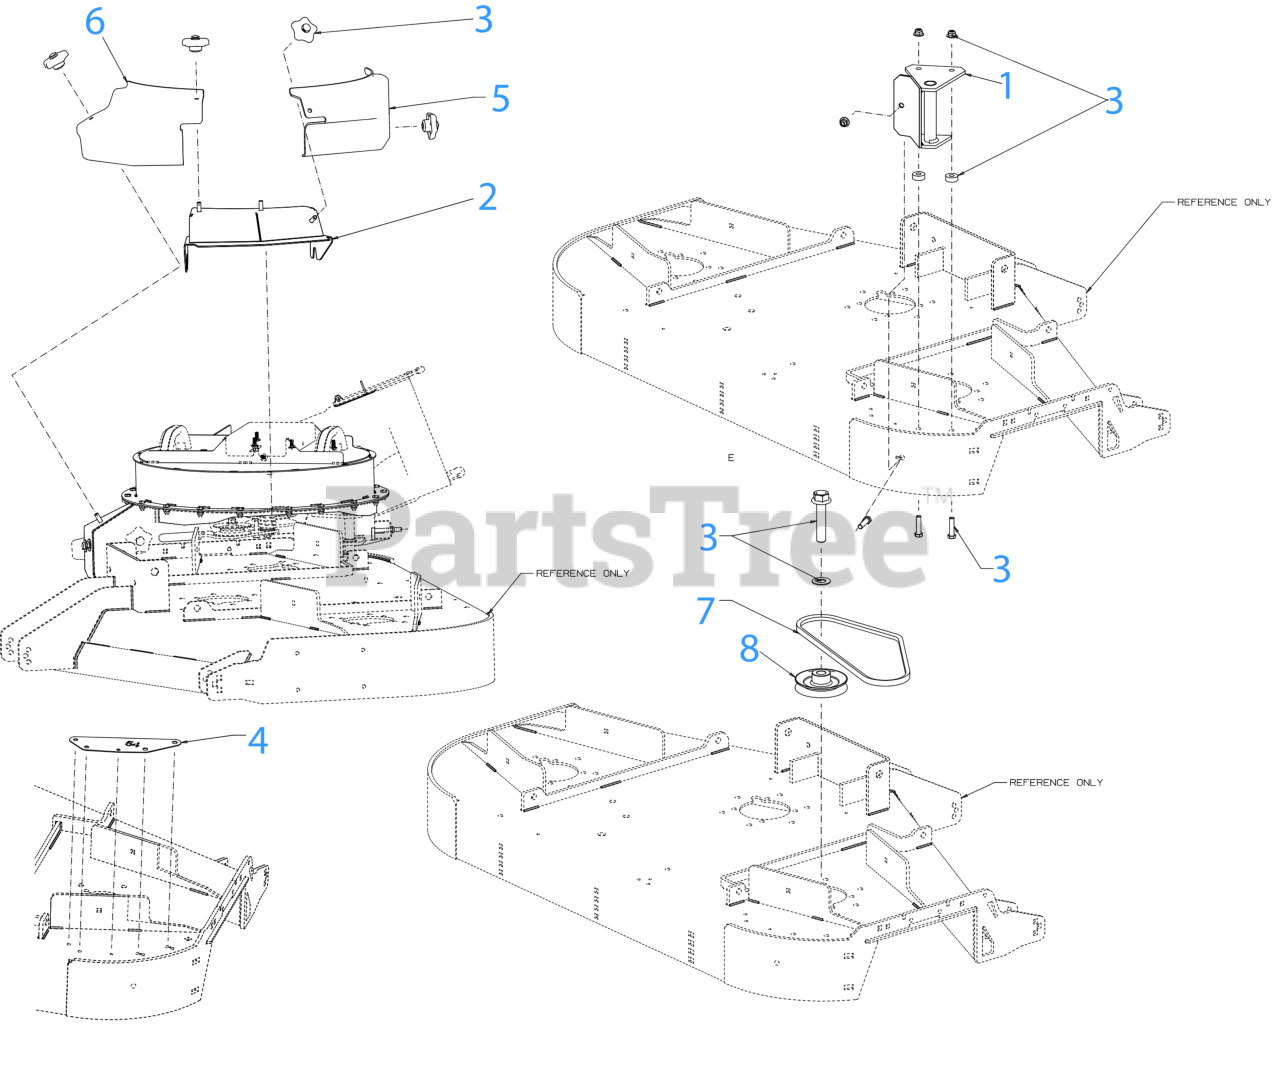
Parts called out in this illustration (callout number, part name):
1	BLOWER MOUNT
2	BELT COVER (CENTER)
3	SCREW PACK
4	TEMPLATE PLATE
5	COVER BELT (REAR)
6	COVER BELT (FRONT)
7	54" BLOWER DRIVE BELT
